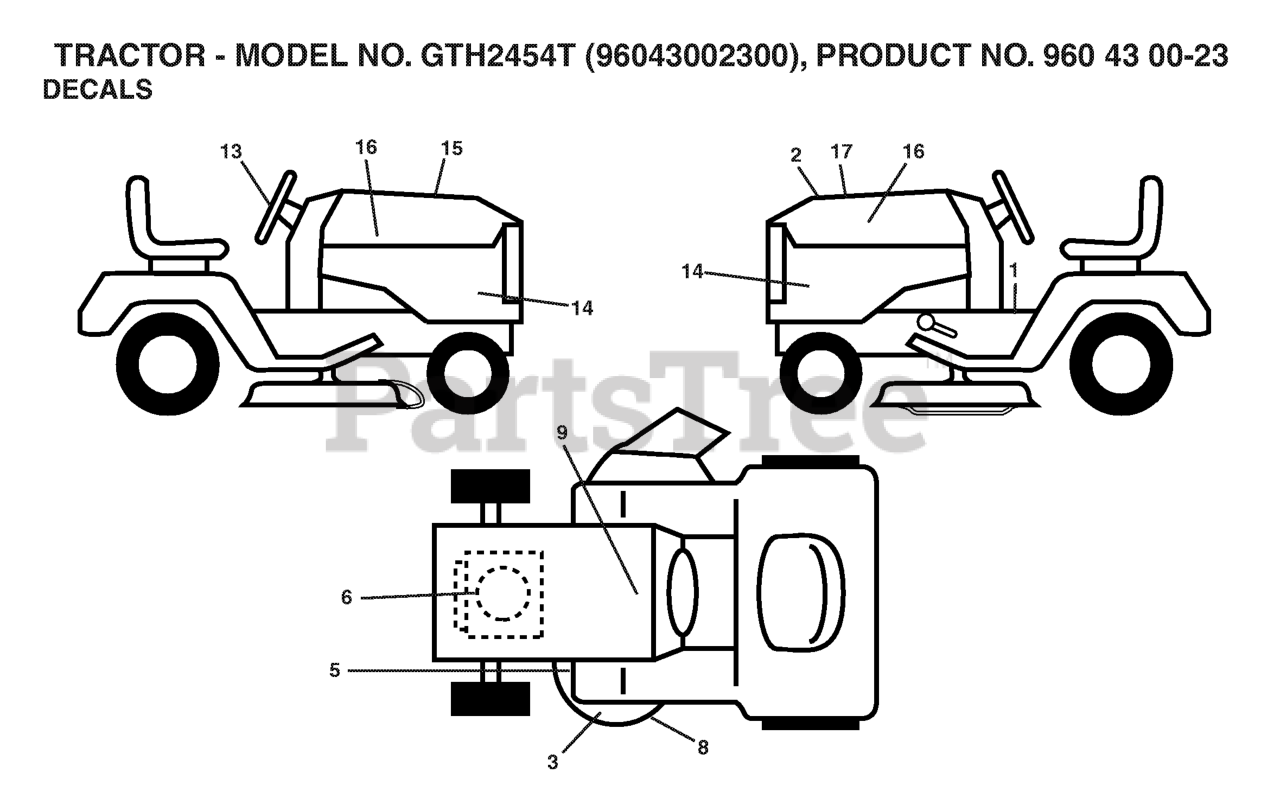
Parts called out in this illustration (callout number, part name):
2	DECAL.HOOD.TOP.INSERT.
3	DECAL.WARN.KEEP.HAND.AWAY
5	DECAL CLUTCH/BRAKE
8	DECAL.MOWER.SCH.48/54
9	DECAL BTRY SYMBOLS
13	DECAL.WHEEL.STRG.LGN.H
15	DECAL HOOD CUST. RESP.
16	DECAL.HOOD.NAMELOGO.HUSQ
